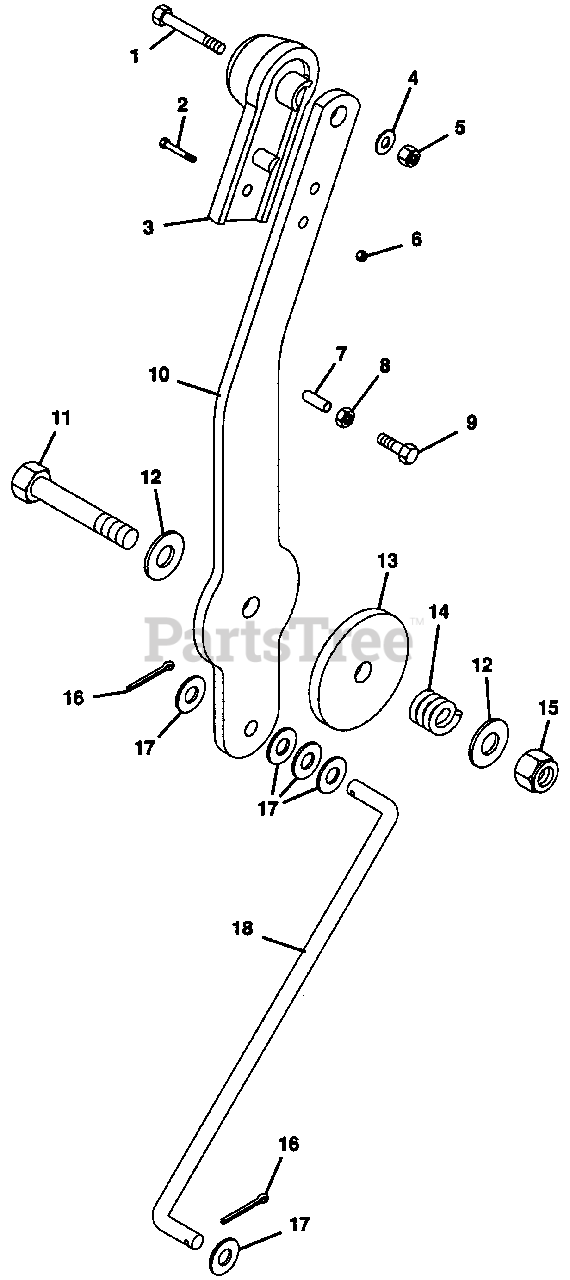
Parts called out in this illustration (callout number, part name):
1	BOLT, HEX 1/4-20 X 1.50
2	SCREW, MACH. 6-32 X .625 PHD
3	KNOB, HANDLE CONTROL
4	WASHER, FLAT .281 X .625 X .065
5	NUT, LOCK 1/4-20
6	NUT, MACH. LOCK 6-32
8	NUT, HEX 1/4-20
9	BOLT, HEX 1/4-20 X .75
10	LEVER, SPEED CONTROL
11	BOLT, HEX 1/2-13 X 2.50
12	WASHER, FLAT .531 X 1.062 X .095
13	DISC, FRICTION MATERIAL
14	SPRING, COMP. 1 X .78 X 388 LB/IN
15	NUT, LOCK 1/2-13
16	PIN, COTTER .094 X 1.00
17	WASHER, FLAT .406 X .812 X .065
18	ROD, SPEED CONTROL
